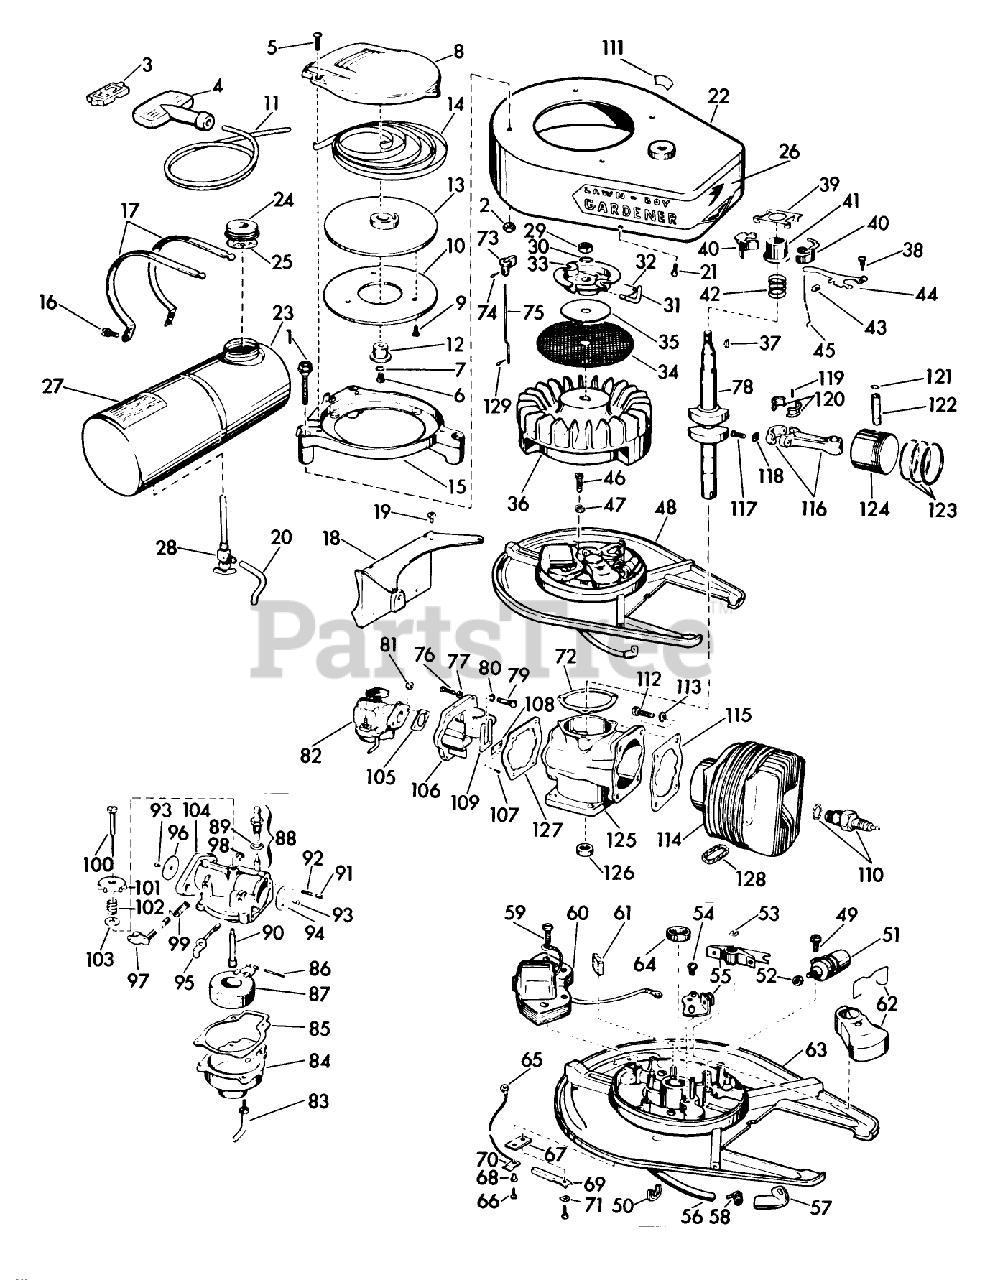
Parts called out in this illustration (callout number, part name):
10	Plate-Pulley
14	RECOIL SPRING
21	SCREW S
24	Gas Cap
27	Decal-Instruction
28	VALVE&SCREEN SM
31	PIN - STARTER
41	COLLAR S
42	Spring-Governor
43	WEAR BLOCK S
44	GOVERNER LEVER AY
45	GOVERNOR ROD S
55	BREAKER AY. S
57	Cover-Rubber
66	Screw Shut-off Switch
71	Washer, Bow
72	GASKET S
73	KNOB, CHOKE BAR
74	Cotter Pin-Choke Knob
76	SCREW S
78	Crankshaft
81	STOP NUT
93	Screw-Choke Disc
99	SPRING
100	NEEDLE AY. S
102	Spring-Ndl. Adj.
105	GASKET S
108	PLATE-BACKUP, REED
110	Spark Plug
111	Decal-Off-on
120	LINER ASM
129	Cotter Pin
